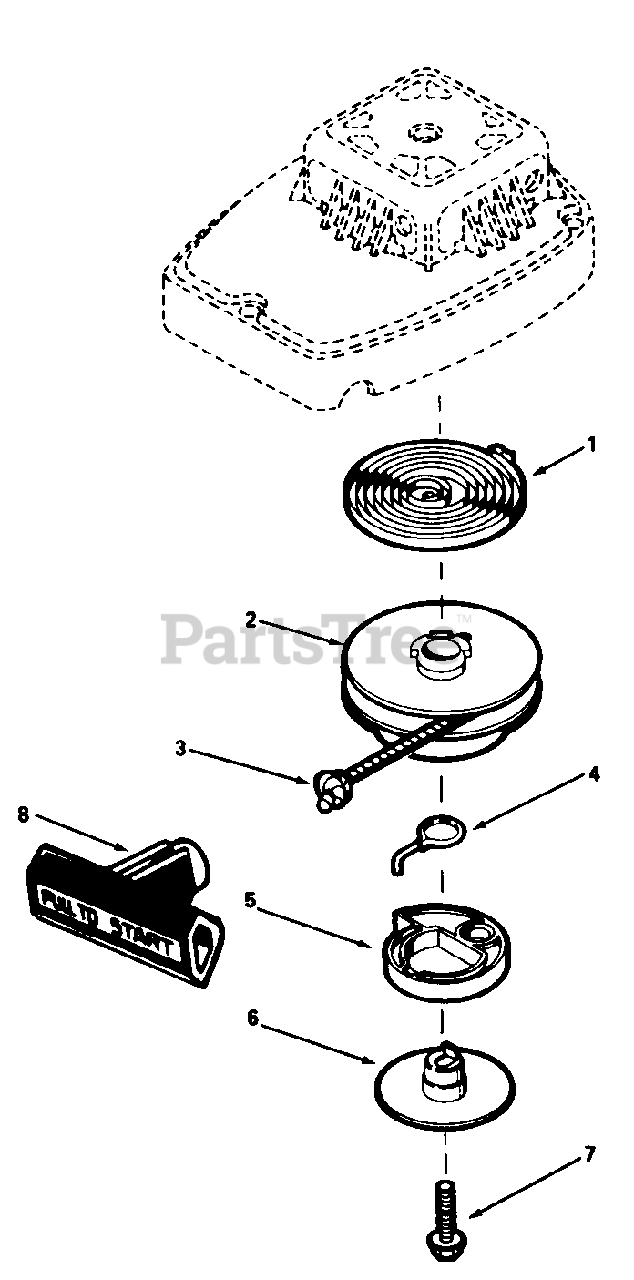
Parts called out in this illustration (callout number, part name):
1	Spring, Rewind
2	Pulley, Starter
3	Rope, Starter (#4 Rope, 71" Long)
4	Spring, Brake
6	Retainer, Pawl
7	Screw, Retainer
8	Handle, Starter
